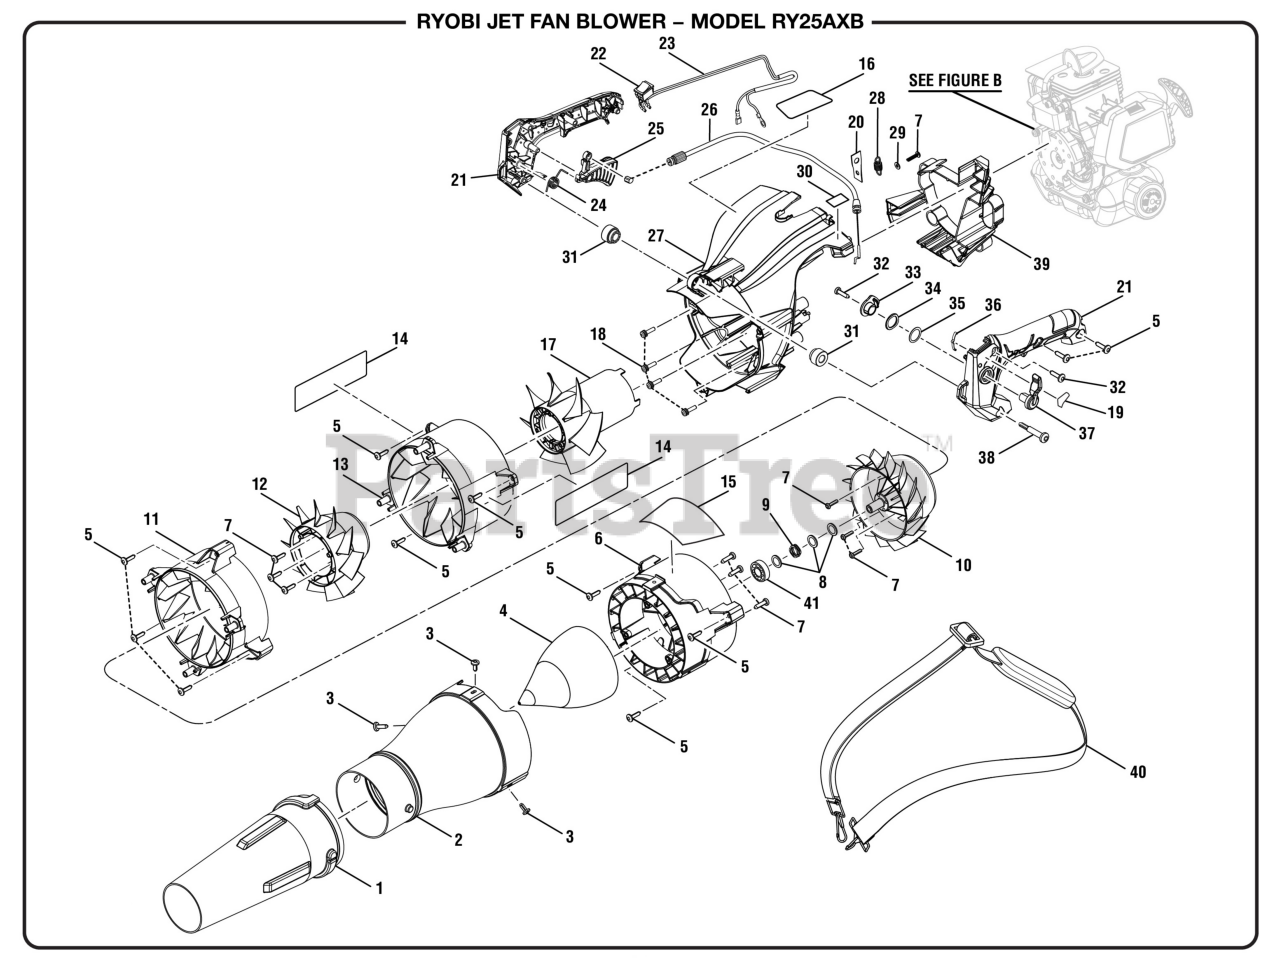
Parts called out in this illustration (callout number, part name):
1	Blower End Nozzle
2	Reducer Nozzle
3	Vacuum Tube Screw (10-14 x 1/2 in., T25 Torx Truss Hd. T.F.)
4	Reducer Cone
5	Screw (10-14 x 19 mm, T25 Torx Truss Pan Hd. T.F.)
6	Axial Stator w/Bearing Assembly Stage 3
7	Screw (M4 x 1.41 mm x 18 mm, T20 Torx Pan Hd. T.F)
8	Washer (OD18 x ID12.15 x 1.5t)
9	Wave Spring
10	Axial Fan (Stage Three)
11	Axial Stator (Stage 2)
12	Axial Fan (Stage Two)
13	Axial Stator (Stage 1)
14	Jet Fan Logo Label
15	Logo Label (Full Crank, 2 cycle)
16	Warning Icon Label
17	Axial Fan (Stage 1)
18	Cap Screw w/Washer (M5 x 16 mm, T25 Torx Soc. Hd.)
19	Cruise Lever Position Label
21	Handle Assembly
22	Stop Switch (Momentary Contact)
23	Wiring Harness w/Fiber Sleeve
24	Torsion Spring (Throttle Trigger)
25	Throttle Trigger
26	Throttle Cable
27	Intake Housing (Inc. Key Nos. 16 and 30)
28	Isolator Spring
29	Flat Washer (OD10 x ID42 x 1t)
30	Primer Bulb Location Label
31	Bushing (Front Isolator)
32	Screw (#10-14 x 3/4 in, T25 Torx Pan Hd. T.F.)
33	Throttle Actuator (Cruise Control)
34	Wavy Washer (217OD x 165ID x 15t)
35	Washer (22.5OD x 16ID x 0.5t)
36	Detent Spring
37	Cruise Control Lever
38	Shoulder Screw (M5 x 40 mm, T25 Torx Truss Hd. T.F.)
39	Intake Guard
40	Shoulder Strap
41	Ball Bearing (6001-zz)
